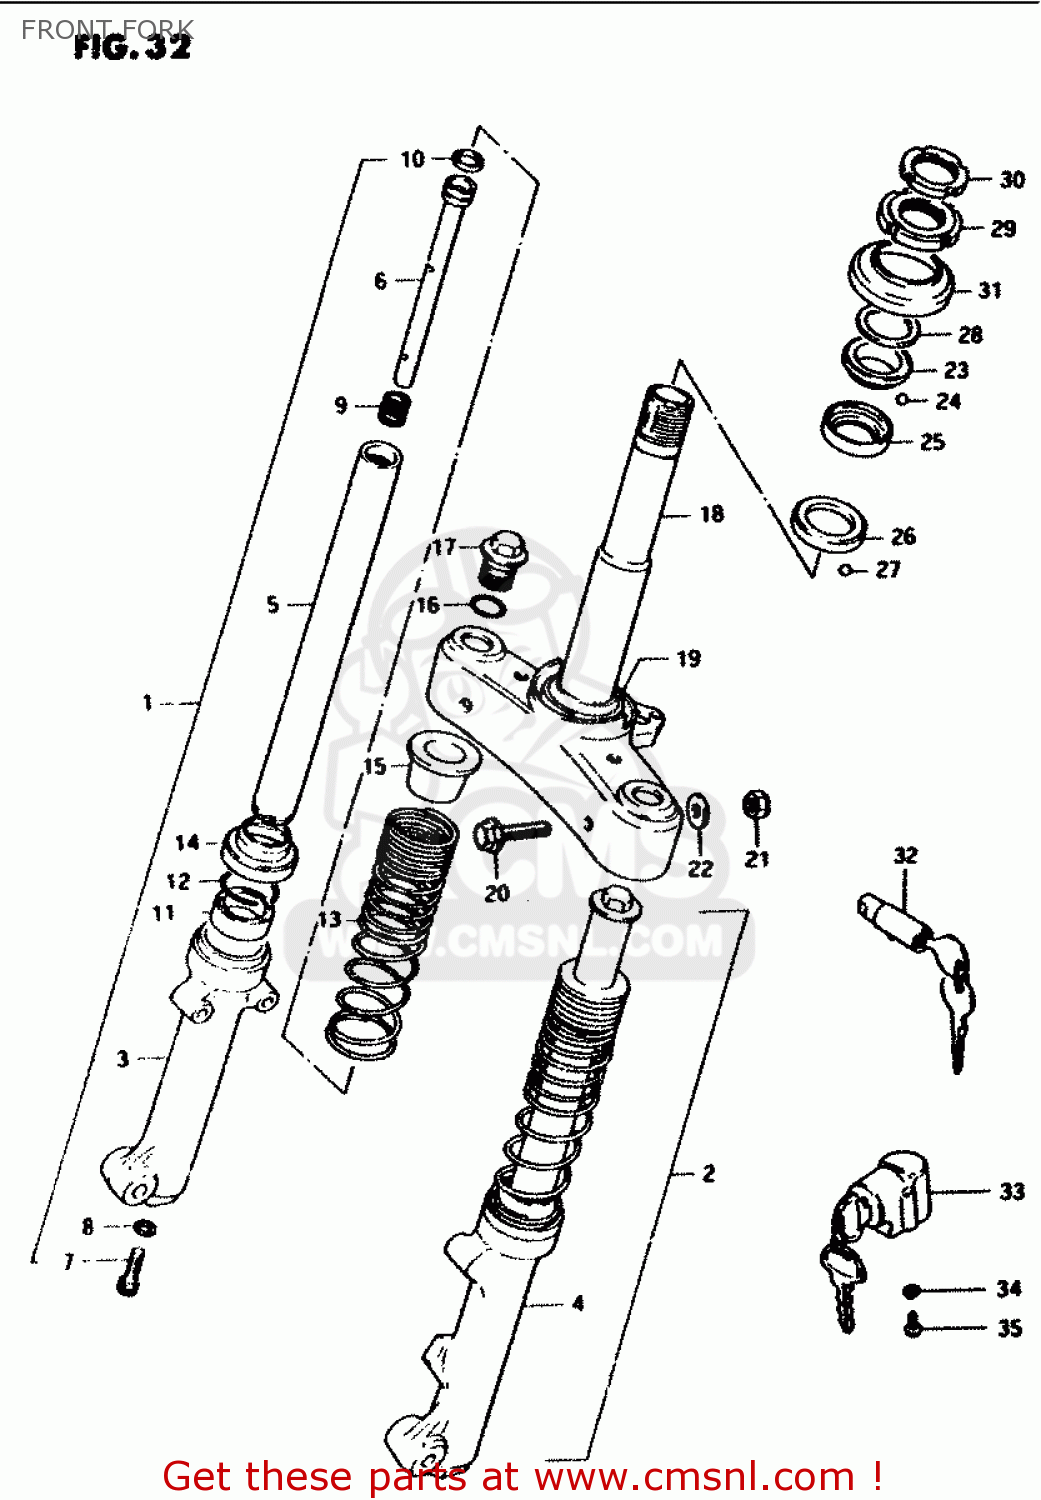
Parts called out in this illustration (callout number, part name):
1	DAMPER ASSY, RH
2	DAMPER ASSY, LH
3	OUTER TUBE, RH
4	OUTER TUBE, LH
5	TUBE,INNER
6	PIPE, SEAT
7	BOLT(8X27)
8	GASKET (NAS)
9	SPRING,REBOUND
10	RING,PISTON
11	SEAL,OIL
12	CIRCLIP,FORK OIL SEAL
13	SPRING
14	DUST SEAL
15	GUIDE,SPRING
16	O-RING,FORK INNER TUBE
17	CAP
18	STEERING STEM
19	RACE,STEERING OUTER LWR
20	BOLT 10X58
21	NUT 10MM
22	WASHER 10MM
23	RACE,STEERING OUTER UPR
24	BALL
25	RACE,STEERING INNER UPR
26	RACE,STEERING INNER LWR
27	BALL
28	WASHER
29	NUT,STEERING STEM(25X44X10)
30	NUT,STEERING STEM LOCK
31	DUST SEAL,STEERING UPR
32	LOCK ASSEMBLY,STEERING (NEI
33	LOCK ASSY,STEERING
34	LOCK WASHER
35	SCREW
